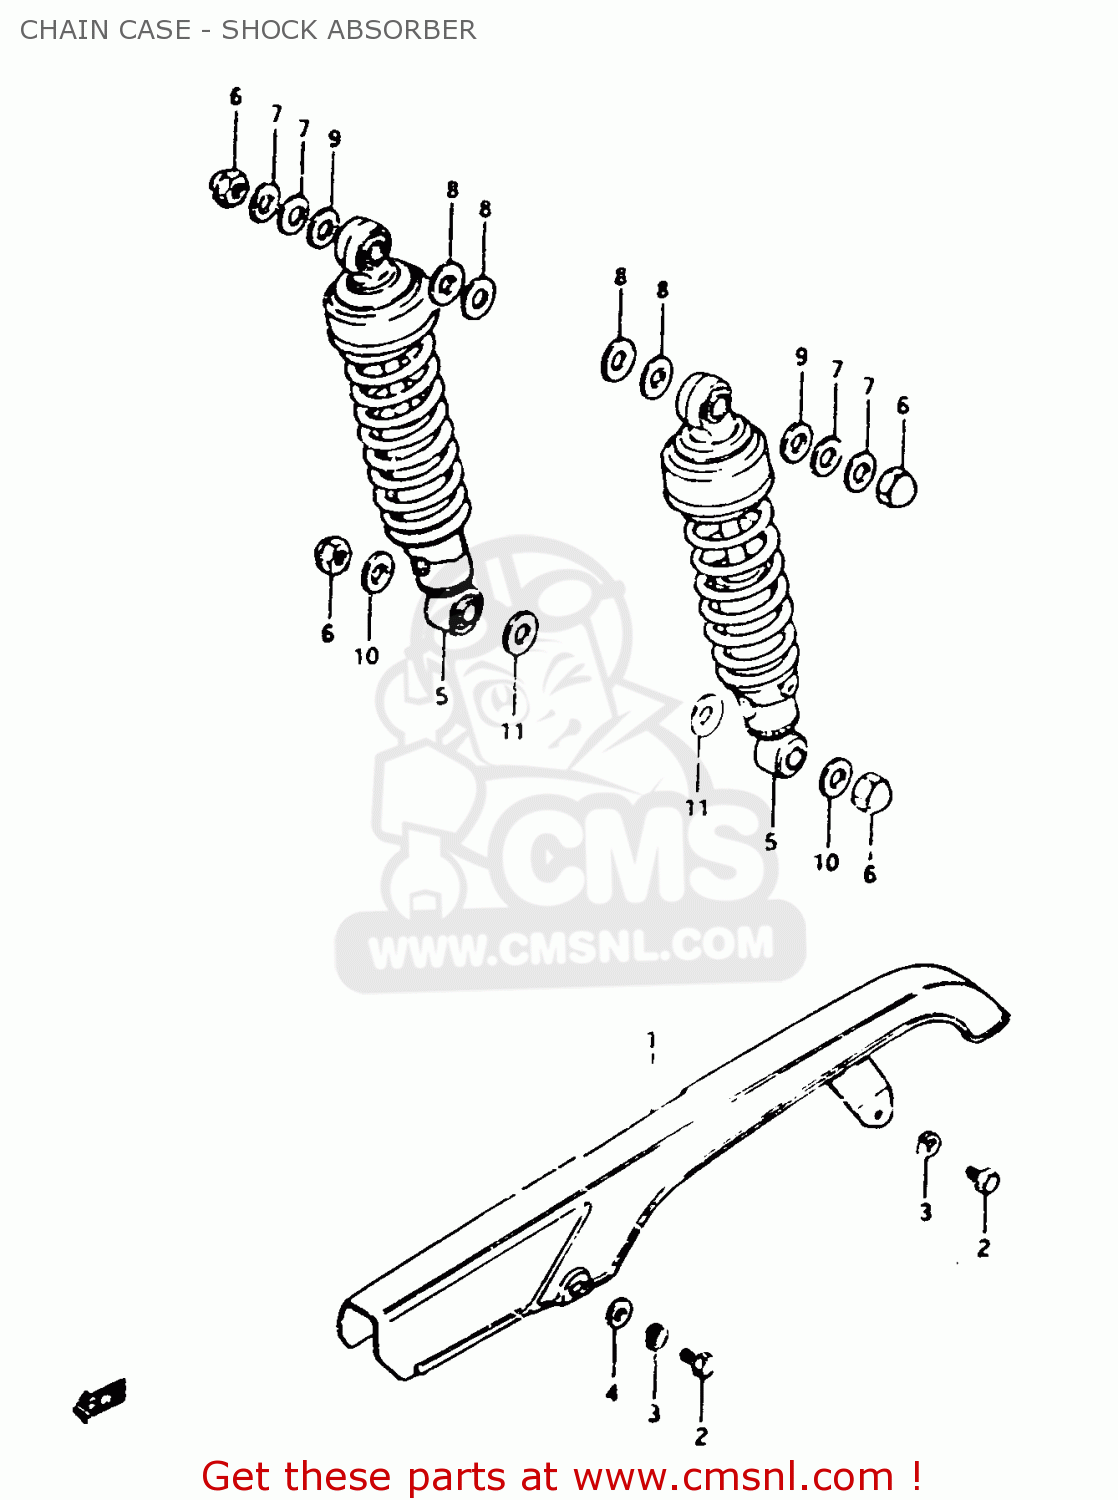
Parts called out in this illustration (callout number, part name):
1	CASE,CHAIN
2	BOLT
3	LOCK WASHER
4	WASHER
5	ABSORBER ASSY,RR SHOCK
6	NUT, LOWER LH
7	WASHER(10.5X24X3.2)
8	WASHER
9	WASHER (12.5X24X3.2)
10	WASHER
11	WASHER (12.5X24X1.6)
